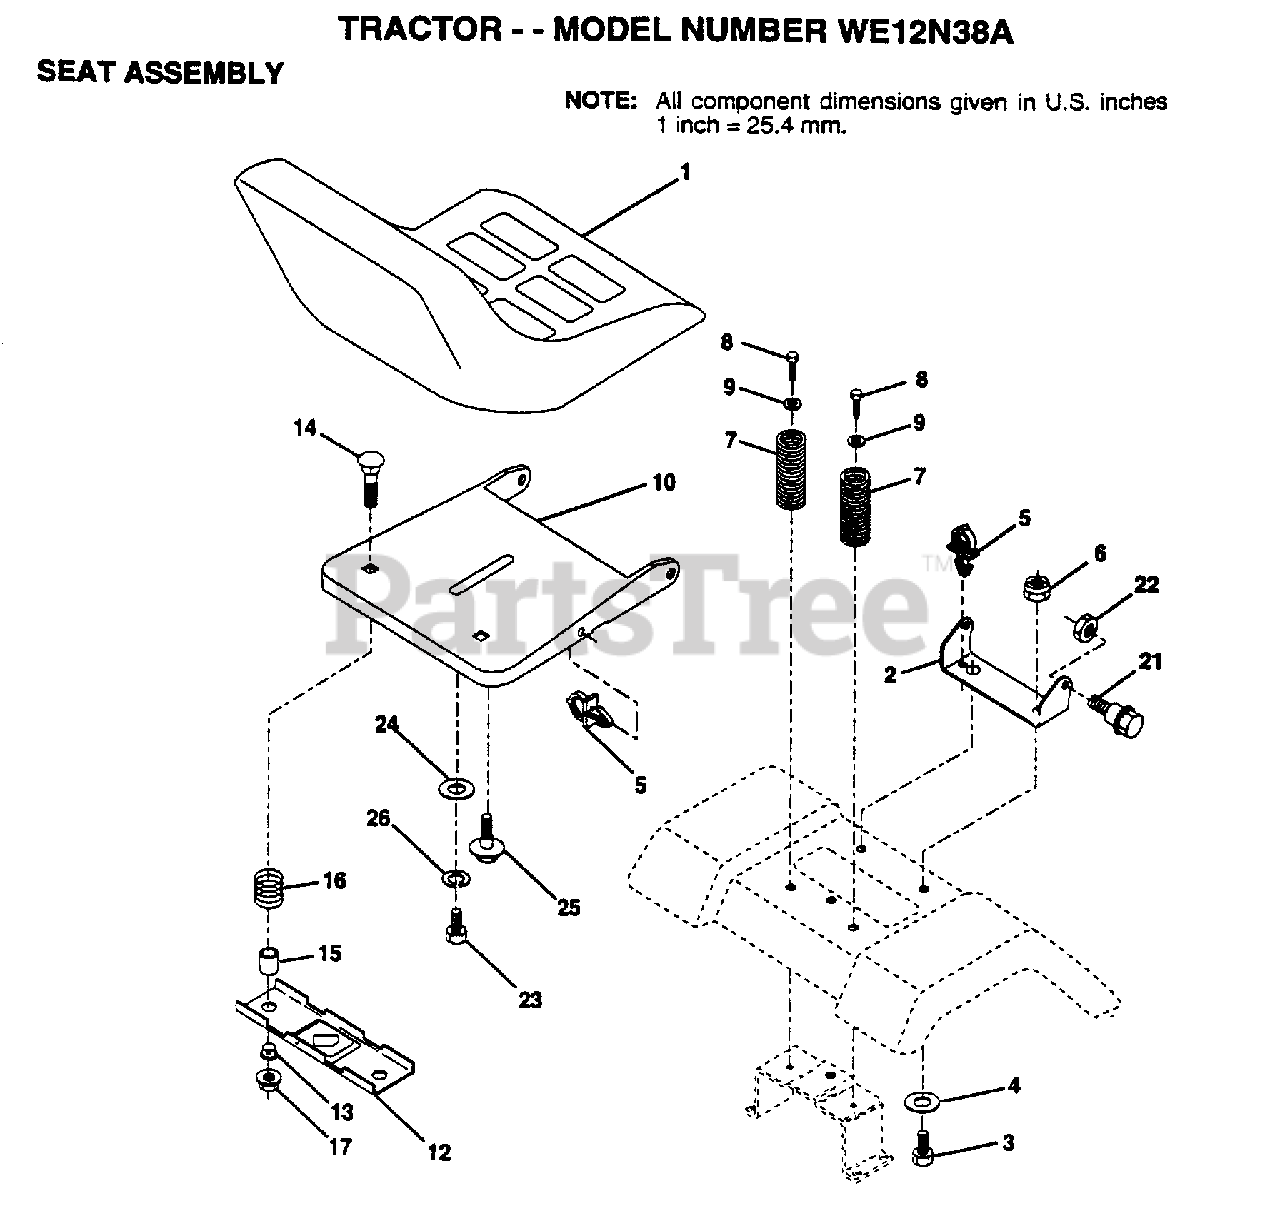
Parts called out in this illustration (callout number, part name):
2	BRACKET PVT SEAT
3	BOLT
4	WASHER PM
5	CLIP.PUSH-IN.HING
6	NUT
7	SPRING COMPRESSIO
8	SCREW GTV
9	WASHER
12	BRKT SWITCH
13	BUSHING
15	SPLIT SPACER
16	SPRING
21	BOLT.SHLD.5/16-18
22	NUT
23	BOLT
24	WASHER
25	"BOLT,SHOULDER"
26	LOCKWASHER
